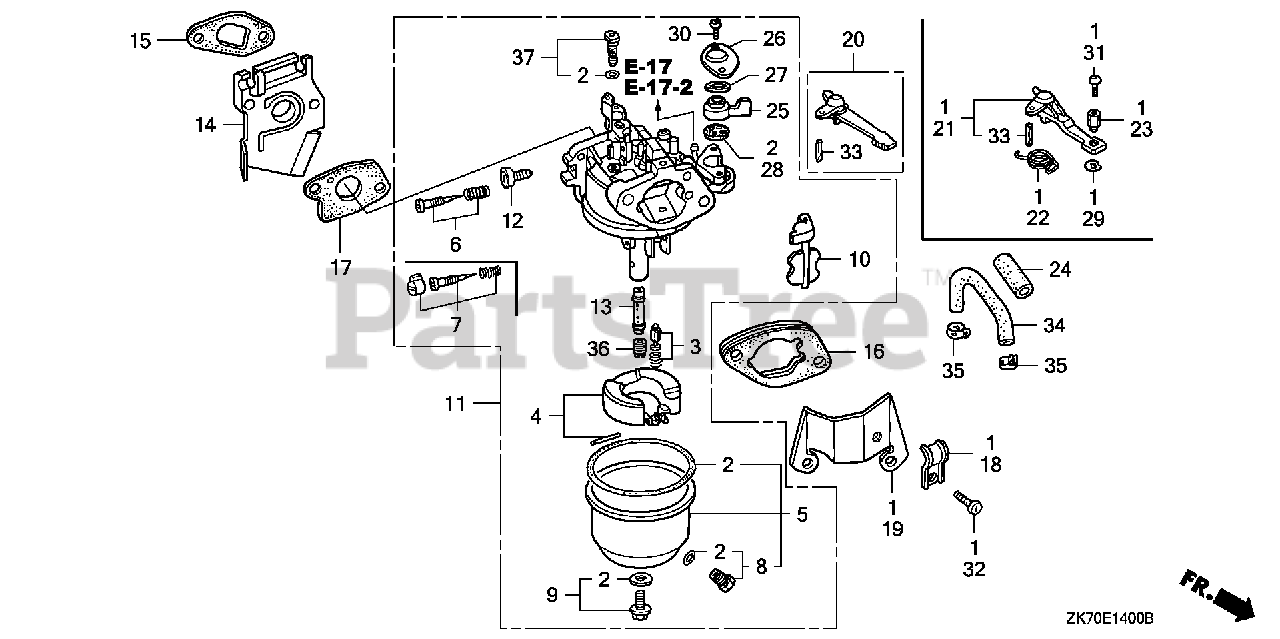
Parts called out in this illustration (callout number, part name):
1	CHOKE KIT, REMOTE CONTROL
2	GASKET SET
3	VALVE SET, FLOAT (SEAT NOT INCLUDED)
4	FLOAT SET
5	CHAMBER SET, FLOAT
6	SCREW SET, PILOT (CARBURETOR NO.)
8	SCREW SET, DRAIN
9	SCREW SET
10	CHOKE SET
11	CARBURETOR ASSY. (BE12B C)
12	SCREW, THROTTLE STOP
13	NOZZLE, MAIN
14	INSULATOR, CARBURETOR
15	GASKET, INSULATOR
16	SPACER, CARBURETOR
17	GASKET, CARBURETOR
18	HOLDER, CONTROL CABLE
19	STAY, CHOKE CONTROL
20	LEVER, CHOKE (STD)
21	LEVER, CHOKE (REMOTE)
22	SPRING, RETURN
23	HOLDER, CABLE
25	LEVER, PETCOCK
26	PLATE, LEVER SETTING
27	SPRING, PETCOCK LEVER
28	GASKET, PETCOCK
29	CIRCLIP (5MM)
30	SCREW, PAN (3X6)
31	SCREW, PAN (4X8)
32	SCREW, PAN (5X8)
33	PIN, SPRING (2X12)
34	BULK HOSE, FUEL (4.5X3000) (4.5X140)
36	JET, MAIN (#55)
36	JET, MAIN (#58)
36	JET, MAIN (#60)
37	JET SET, PILOT (#35)
